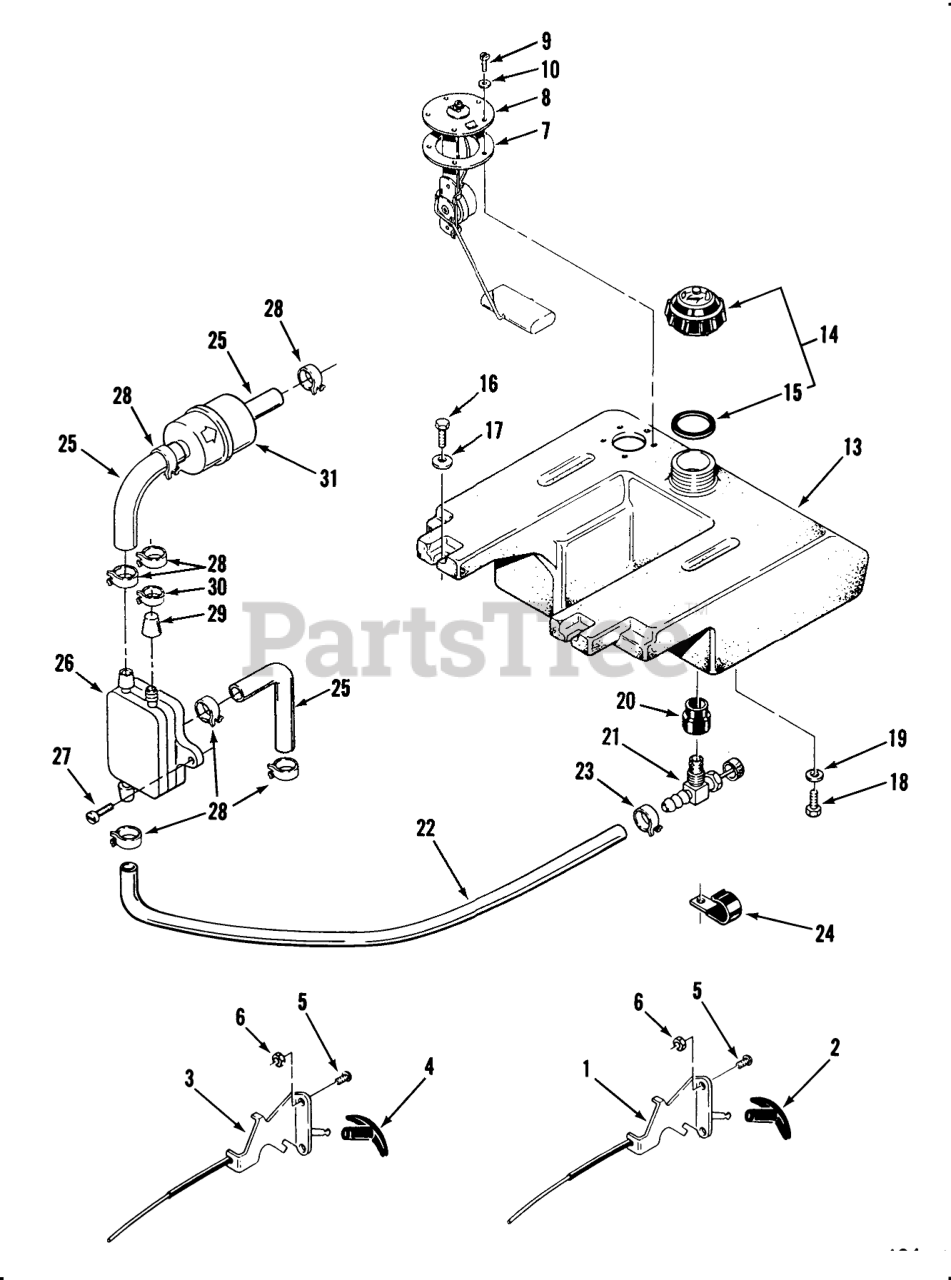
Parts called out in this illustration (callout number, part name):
1	Throttle Control
2	KNOB-THROTTLE
3	CONTROL-CHOKE
4	KNOB-CHOKE
5	SCRW-PHC
6	Nut
7	GASKET-SENDER, FUEL
8	SENDER-FUEL LEVEL
9	Screw
10	Lockwasher
13	Fuel Tank (Includes items 20 & 21)
14	ASS'Y-GAS CAP
15	GASKET-GAS CAP
16	Bolt
17	Washer
18	Bolt
19	Lockwasher
20	BUSHING
21	VALVE-FUEL
22	Line-Fuel 53"
23	Clamp
24	Clamp
24	CLAMP
25	Hose
26	Fuel Pump
27	Screw
28	Clamp
29	Cap
30	Clamp
31	Filter-Fuel
